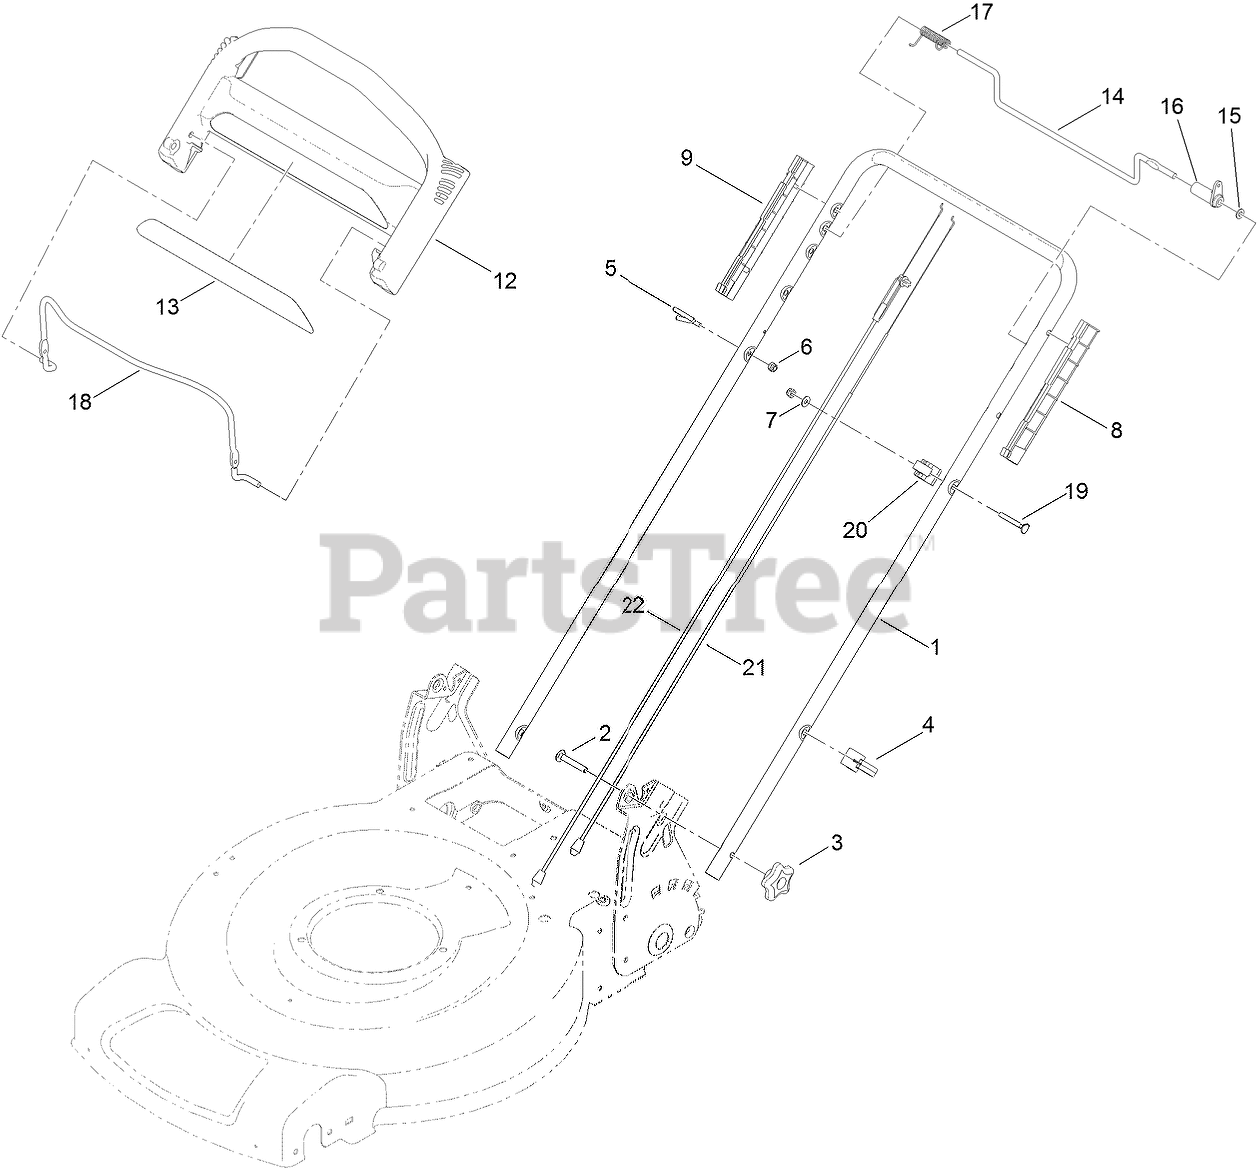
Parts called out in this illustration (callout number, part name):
2	Screw-CARR
3	KNOB-HANDLE
4	GUIDE-CABLE
5	GUIDE-ROPE
6	NUT-LOCK, NI
7	WASHER-FLAT
8	GUIDE-LH
9	GUIDE-RH
12	HANDLE-CONTROL
14	BAR-CONTROL, TRACTION
15	WASHER-PLAIN
16	LEVER-TRACTION
17	Spring-Torsion
18	Bail-Brake
19	SCREW
20	ANCHOR-CABLE
21	CABLE-TRACTION
22	CABLE-BRAKE
